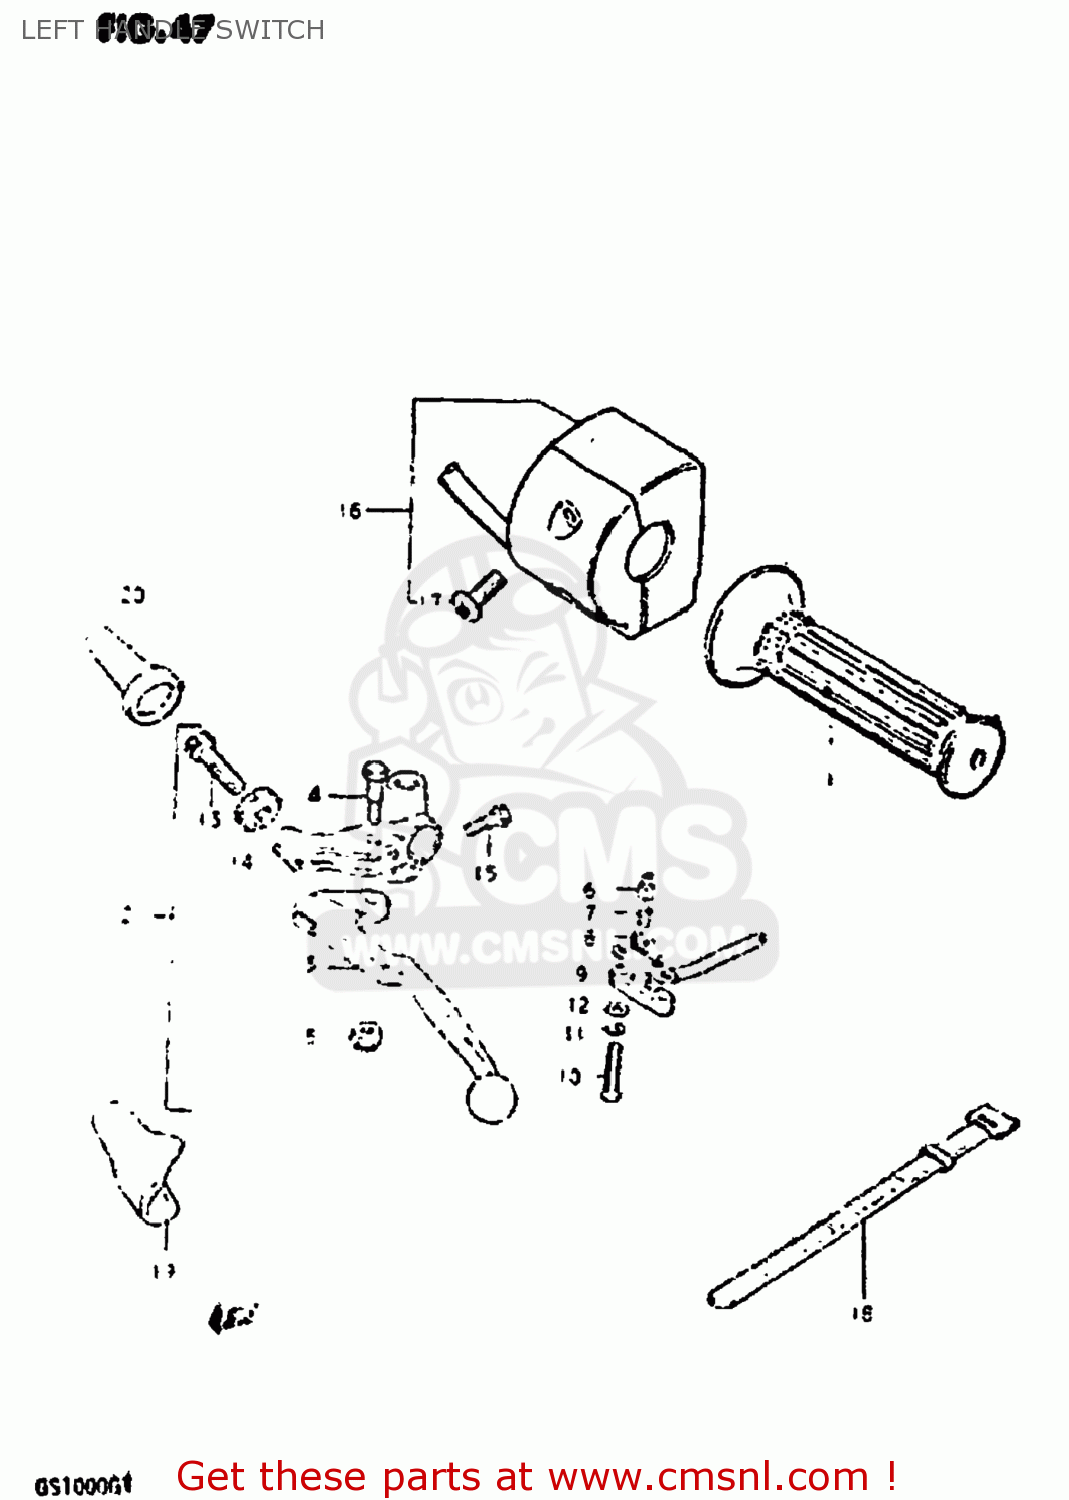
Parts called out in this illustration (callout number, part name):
1	GRIP,LEFT
2	LEVER ASSEMBLY
3	LEVER,CLUTCH
4	BOLT,LEVER
5	NUT 6MM
6	HOLDER
7	SPRING
8	PLATE
9	COVER,FR BK TERMINAL BASE
10	SCREW
11	LOCK WASHER
12	WASHER
13	ADJUSTER,CABLE
14	NUT,CABLE ADJUSTER
15	BOLT,CLUTCH LEVER HOLDER
16	SWITCH ASSEMBLY,HANDLE,LEFT
17	SCREW
18	CLAMP(L:120)
19	COVER,CLUTCH LEVER
20	BOOT,CLUTCH CABLE
